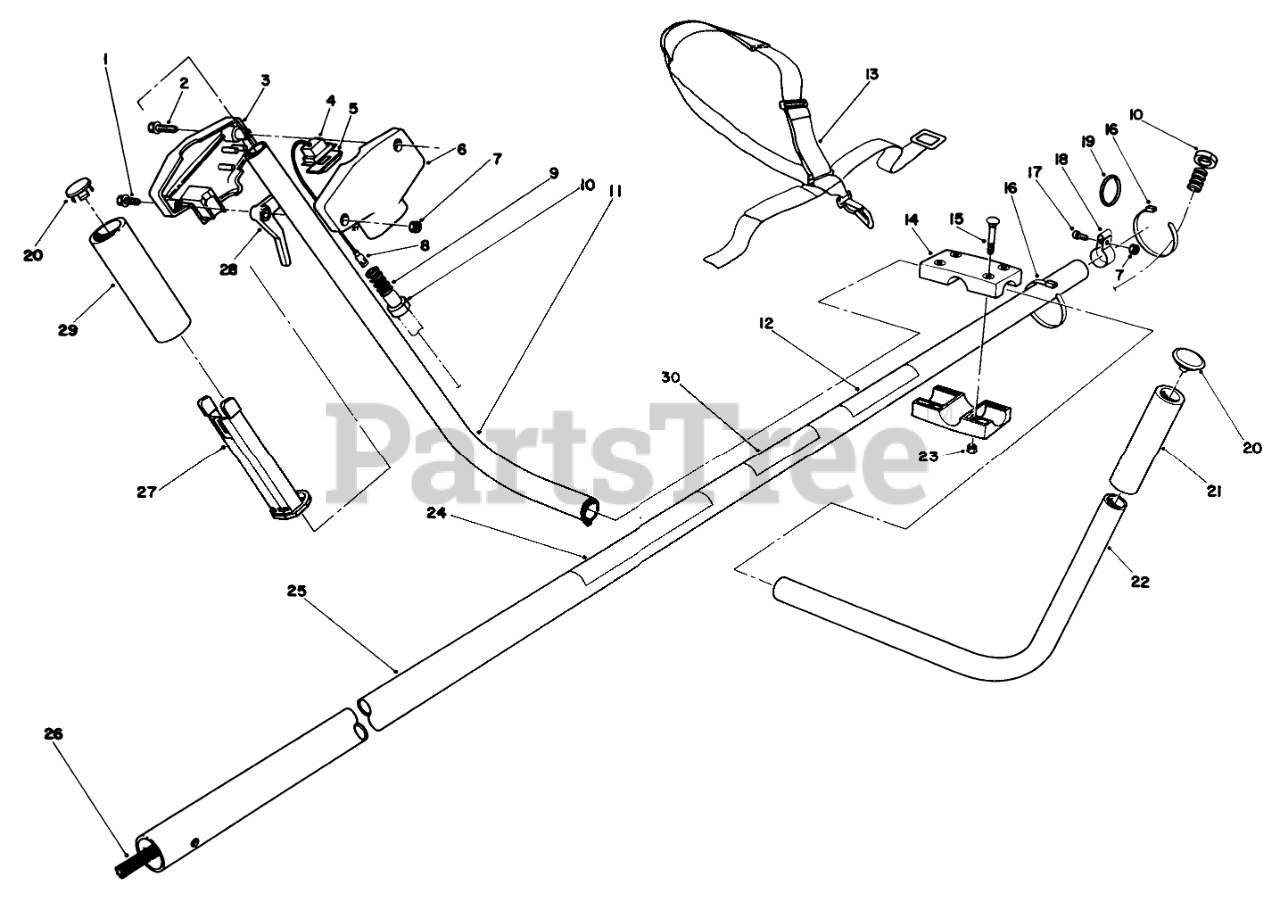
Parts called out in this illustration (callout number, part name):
1	SCREW-HWH
3	THROTTLE HSG R H 1"
4	SWITCH
5	SWITCH COVER-BLACK
6	THROTTLE HSG L H 1"
7	NUT-LOCK, NI
8	WIRE ASM
9	Cover-Cable
10	RING FITTING
11	RH HANDLE
12	Decal Danger
13	Harness-Shoulder
14	CLAMP
15	Carriage Bolt
16	TIE-CABLE
17	SCREW-SRH
18	HARNESS CLAMP
19	RING-HARNESS
20	TUBE CLOSURE
21	FOAM GRIP
22	LH HANDLE
23	NUT-LOCK, NI
24	DECAL
25	TUBE ASM
26	SPLINE SHAFT
27	TROUGH
28	THROTTLE LEVER
29	GRIP-RUBBER
30	DECAL-INSTRUCTION
